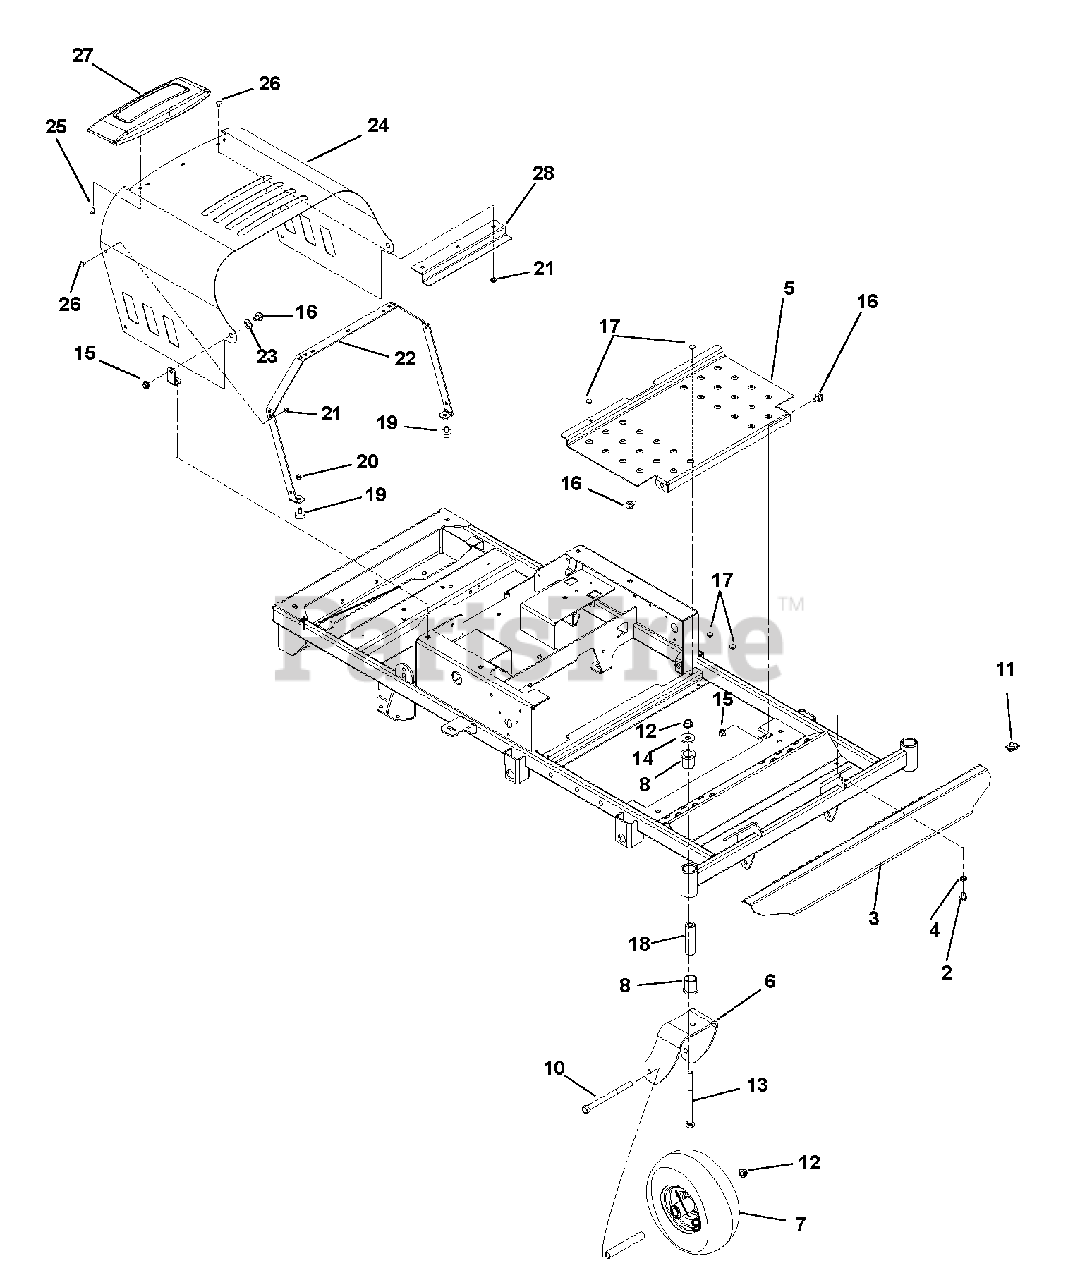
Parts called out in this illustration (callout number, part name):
1	Weldment, Frame XL
2	Bolt, Hex .38-16 x 1.00 Grade 5
3	Weldment, Footrest
4	Washer, Locking .38 x .094 Regular
5	Deck Access Panel
6	Fork, Caster
7	Wheel/Tire Assembly, 11.0 x 4.0 x 5.0, Monitor
8	Bushing, Flange 1.00 x 1.25 x 1.50 x 1.50
9	Spacer, Wheel
10	Bolt, Hex .50-13 x 6.50 Grade 5
11	Nut, Retainer .375-16 x .37
12	Nut, Locking Top Flange .50-13
13	Bolt, Hex .50-13 x 5.00 Grade 5
14	Washer, Flat Steel .511 x 1.441 x .125
15	Nut, Locking Top Flange .38-16
16	Bolt, Shoulder .375-16 x .135
17	Bumper Grommet .125 x .250 Diameter
18	Spacer, Caster Fork
19	Bumper, Rubber
20	Nut, Locking Top Flange .31-18
21	Nut, Locking Top Flange .25-20
22	Bracket, Hood Brace
23	Washer, Flat Nylon .52 x 1.00 x .08
24	Hood, XL
25	Screw, .25 x .50 PN Head
26	Bolt, Round Head Square Neck .25-20 x .50 Grade 5
27	Trim – ZT XL Hood Flat
28	Bracket, Engine Guard
